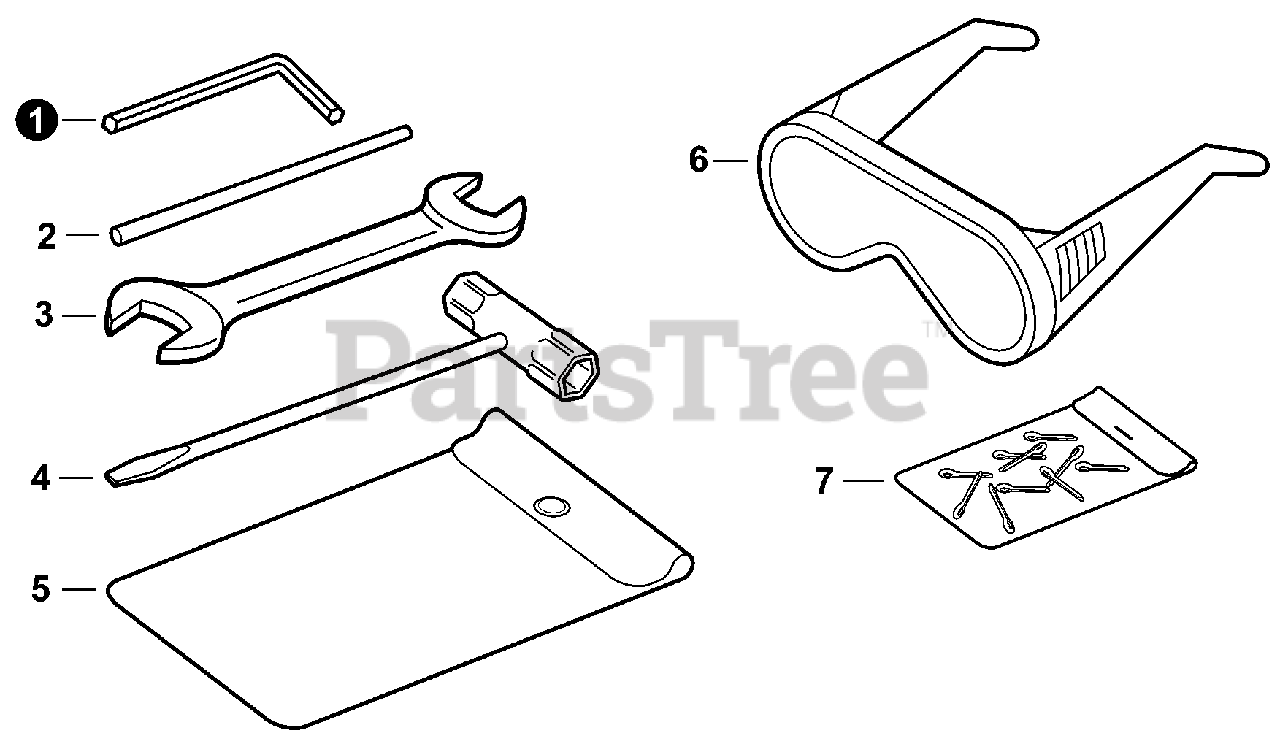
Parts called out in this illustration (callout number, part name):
1	WRENCH, T27 80×30
2	TOOL, LOCKING 5×120 MM
3	SPANNER 8×10
4	T-WRENCH 17×19 L200
5	BAG, TOOL
6	GLASSES, SAFETY
7	PIN, COTTER 2×22
